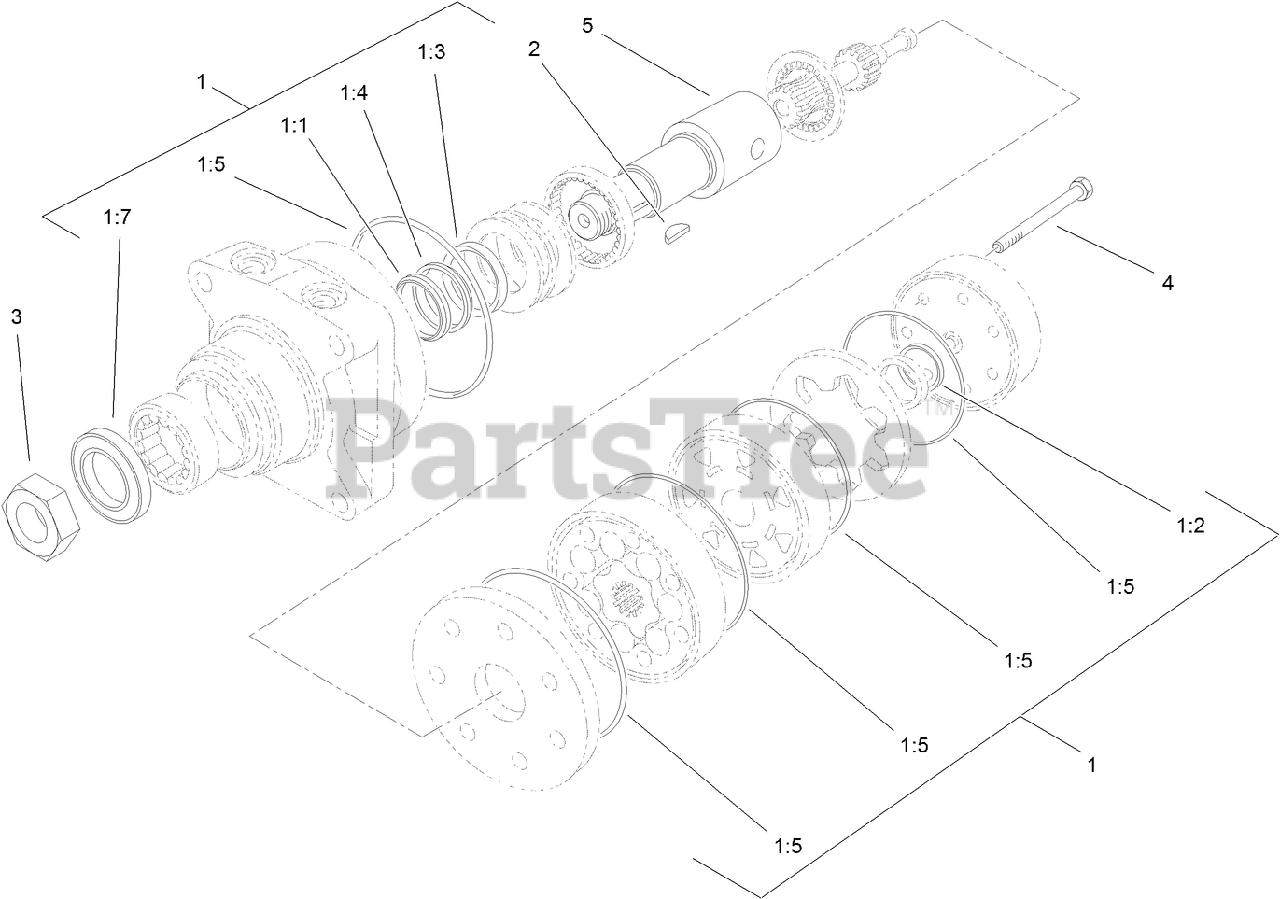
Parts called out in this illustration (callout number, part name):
1	SEAL KIT
1:1	Ring-Back Up
1:2	Seal-Commutator
1:3	SEAL-SHAFT (VITON)
1:4	WASHER-BACK UP, STEEL
1:5	RING-SEAL (VITON)
1:7	Seal-Dirt and Water
2	KEY-WOODRUFF
3	NUT-MOTOR, WHEEL
4	BOLT-SPECIAL
5	SHAFT-COUPLING
